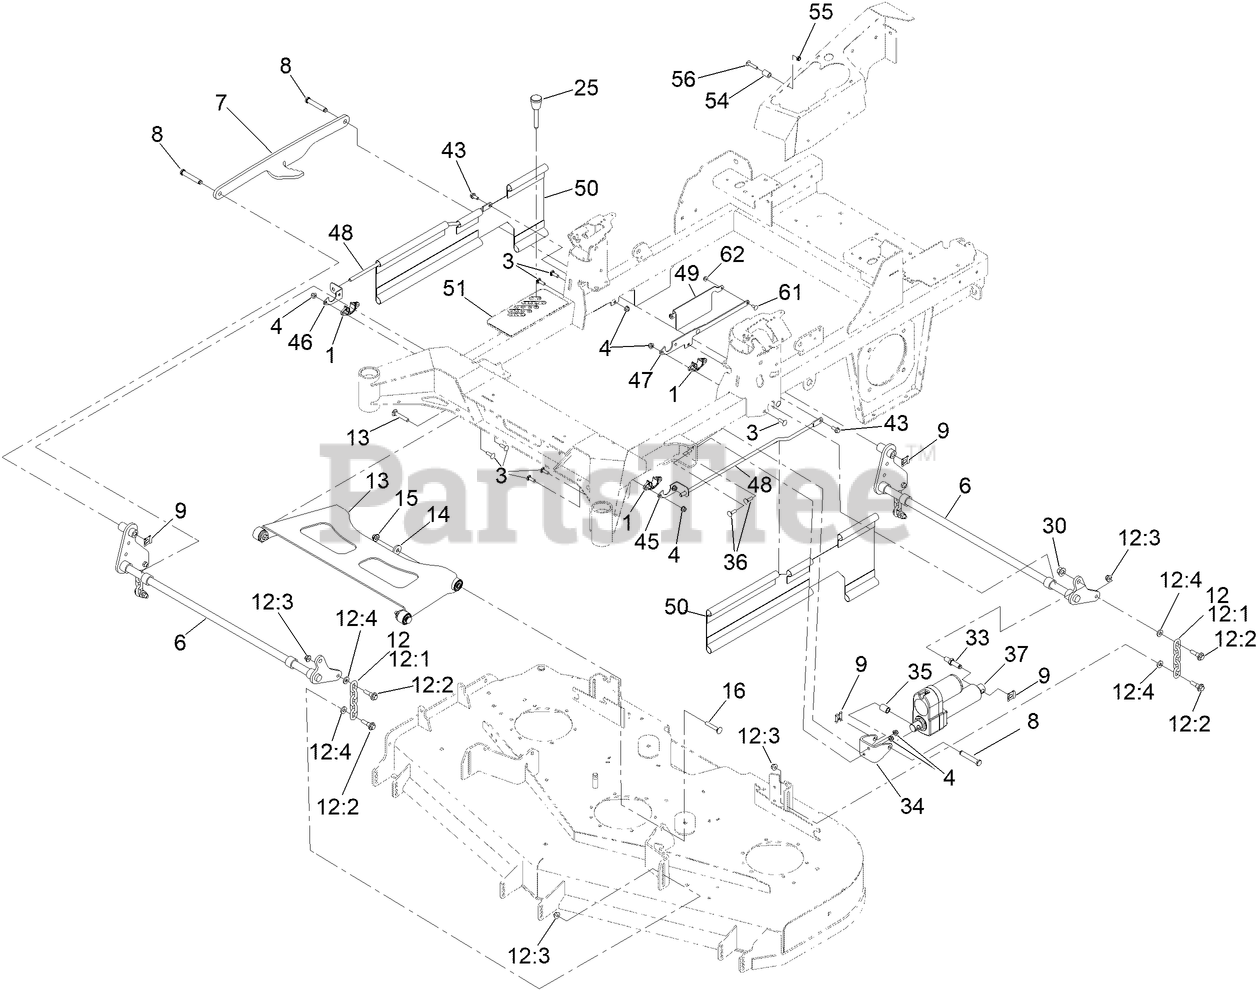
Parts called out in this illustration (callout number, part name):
1	BUSHING-FLANGE
3	SCREW-CARR
4	NUT-HF, NI
6	DECK LIFT SHAFT ASM [BLACK]
7	LINK-LIFT
8	PIN-CLEVIS
9	CLIP-PIN
12	DECK CHAIN ASM
12:1	CHAIN-LIFT, DECK
12:2	BOLT-SHOULDER
12:3	NUT-HF, NI
12:4	SPACER
13	ASM-DECK STRUT W/ BUSHINGS
14	WASHER
15	NUT-FLANGE, NI
16	SCREW-CARR
25	PIN-HOC
30	NUT-LOCK
33	PIN-PIVOT, ACTUATOR
34	CYL MOUNT PLATE
35	SPACER-ALUMINUM
36	BOLT-CARR
37	ACTUATOR-LINEAR
43	SCREW-HHF
45	BRACKET-MOUNT, UPPER FRONT (LH)
46	BRACKET-MOUNT, UPPER FRONT (RH)
47	BRACKET-MOUNTING, UPPER
48	ROD-SUPPORT, UPPER
49	BRACKET-FLAG
50	GUARD-SIDE
51	DECAL-HOC, MM
54	SPACER
55	NUT-LOCK, NI
56	SCREW-TORX
61	SCREW-CARR
62	NUT-HF
